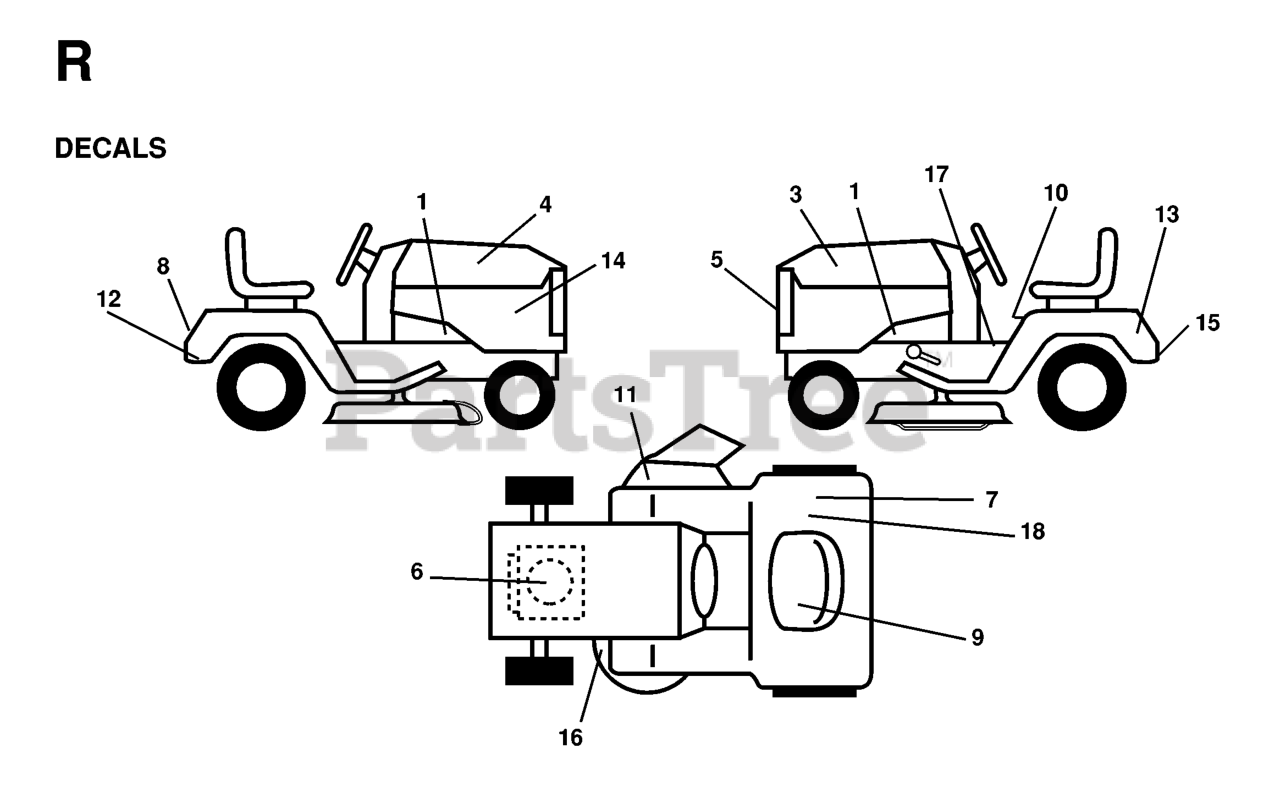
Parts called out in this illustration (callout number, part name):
5	DECAL.GRILLE.HUSQ
6	DECAL HP ENGINE
7	DECAL CERTIFICATION
8	DECAL FENDER HUSQ
9	DECAL BTRY SYMBOLS
10	DECAL READ OWNER'S MAN SYMS
11	DECAL MOWER CUT/FINGER
12	DECAL
13	DECAL, FENDER
15	DECAL
16	DECAL
17	Decal, Brake/Clutch Symbols
18	DECAL EUROPE STANDARD CE
